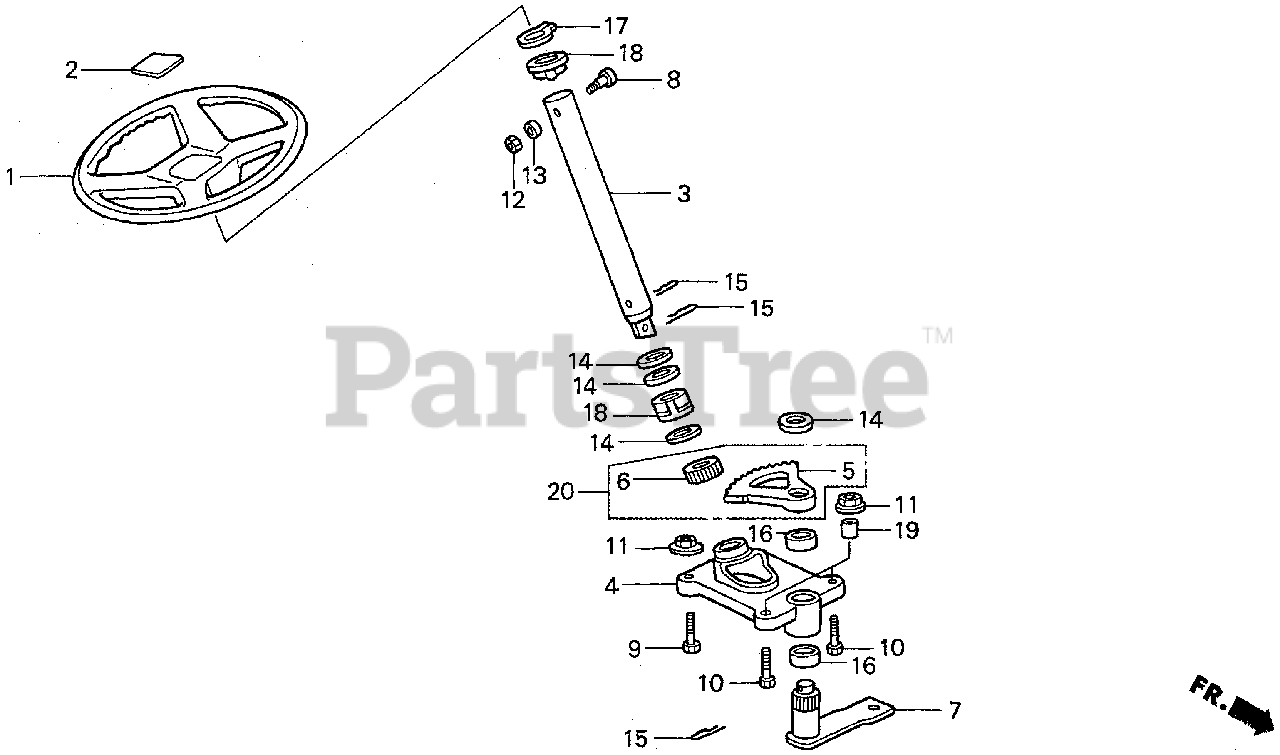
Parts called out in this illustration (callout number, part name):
1	WHEEL, STEERING
2	CAP, STEERING
3	SHAFT, STEERING
4	CASE, STEERING GEAR
5	STEERING GEAR SET
6	STEERING GEAR SET
7	ARM, PITMAN
8	BOLT, HUB STEERING
8	BOLT, STEERING HUB
9	BOLT, HEX. (8X25)
10	BOLT, HEX. (8X50)
11	NUT, FLANGE (8MM)
12	NUT, SELF-LOCK (#10-24)
12	NUT, SELF-LOCK (5MM)
13	WASHER (1/2")
14	WASHER A, WHEEL
15	PIN, COTTER (4X32)
16	BEARING, SECTOR SHAFT
17	RING, WHEEL SNAP
18	BUSH, STEERING SHAFT
19	COLLAR, STEERING
20	STEERING GEAR SET
